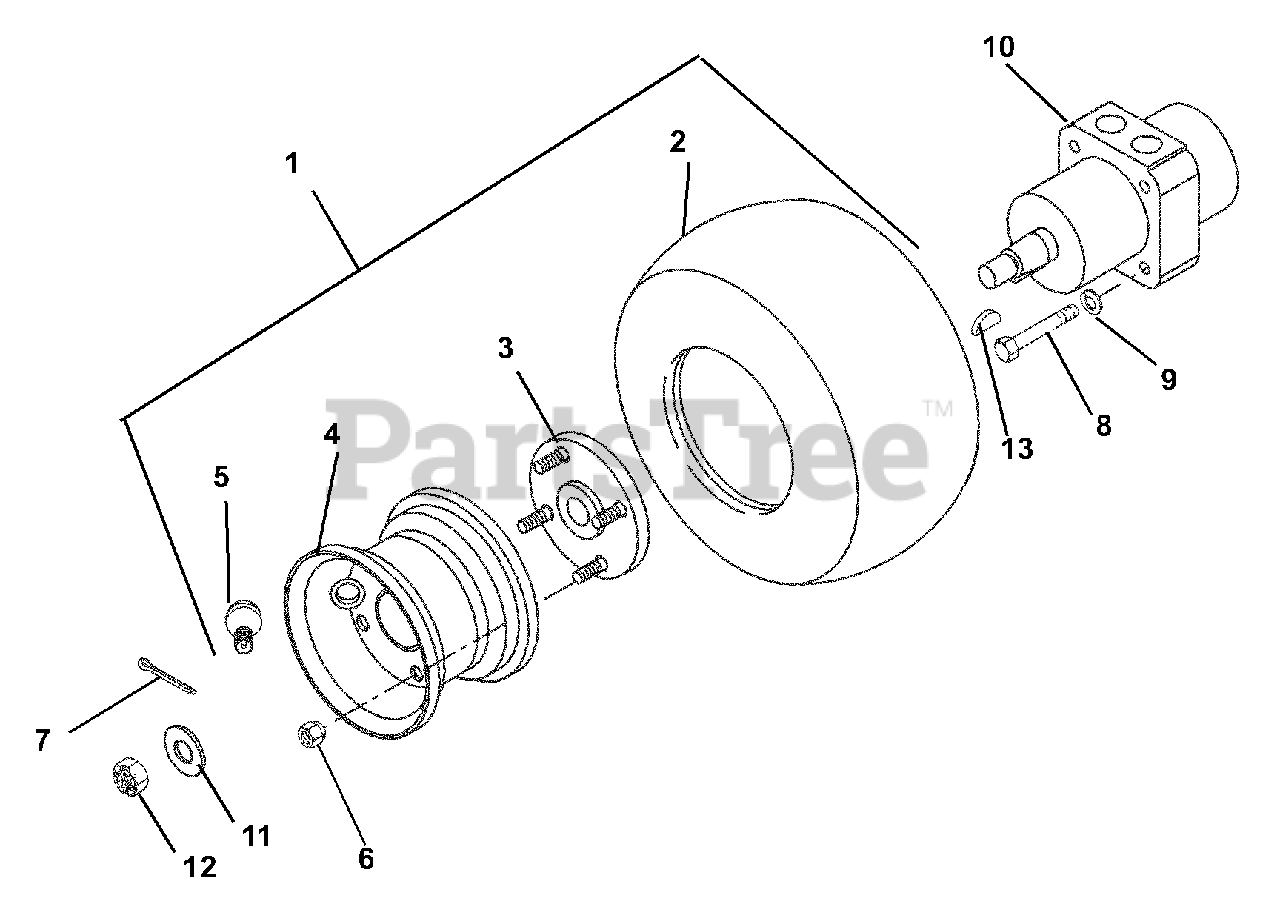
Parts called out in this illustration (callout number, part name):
1	ASSY,WHL & TIRE 18X850
2	TIRE, 18X850-8 4PLY
3	ASSY, HUB W/STUDS
4	ASSY, WHEEL
5	VALVE STEM ASS'Y
6	NUT-LUG .50-20 YWZC
7	@PIN-CTR .12X1.25 EXTPRSQCT YZ
8	@BLT-HEX .38-16X1.00 GR5 YWZC
9	@WSHR-LK .38X.094 REG YWZC
10	MOTOR, HYD WHEEL
11	WSHR-FL-STL.755X1.375X.062YWZC
12	NUT,HEX 3/4-28 SLOTTED
13	KEY-WDRF .19X.75 HRD #9
